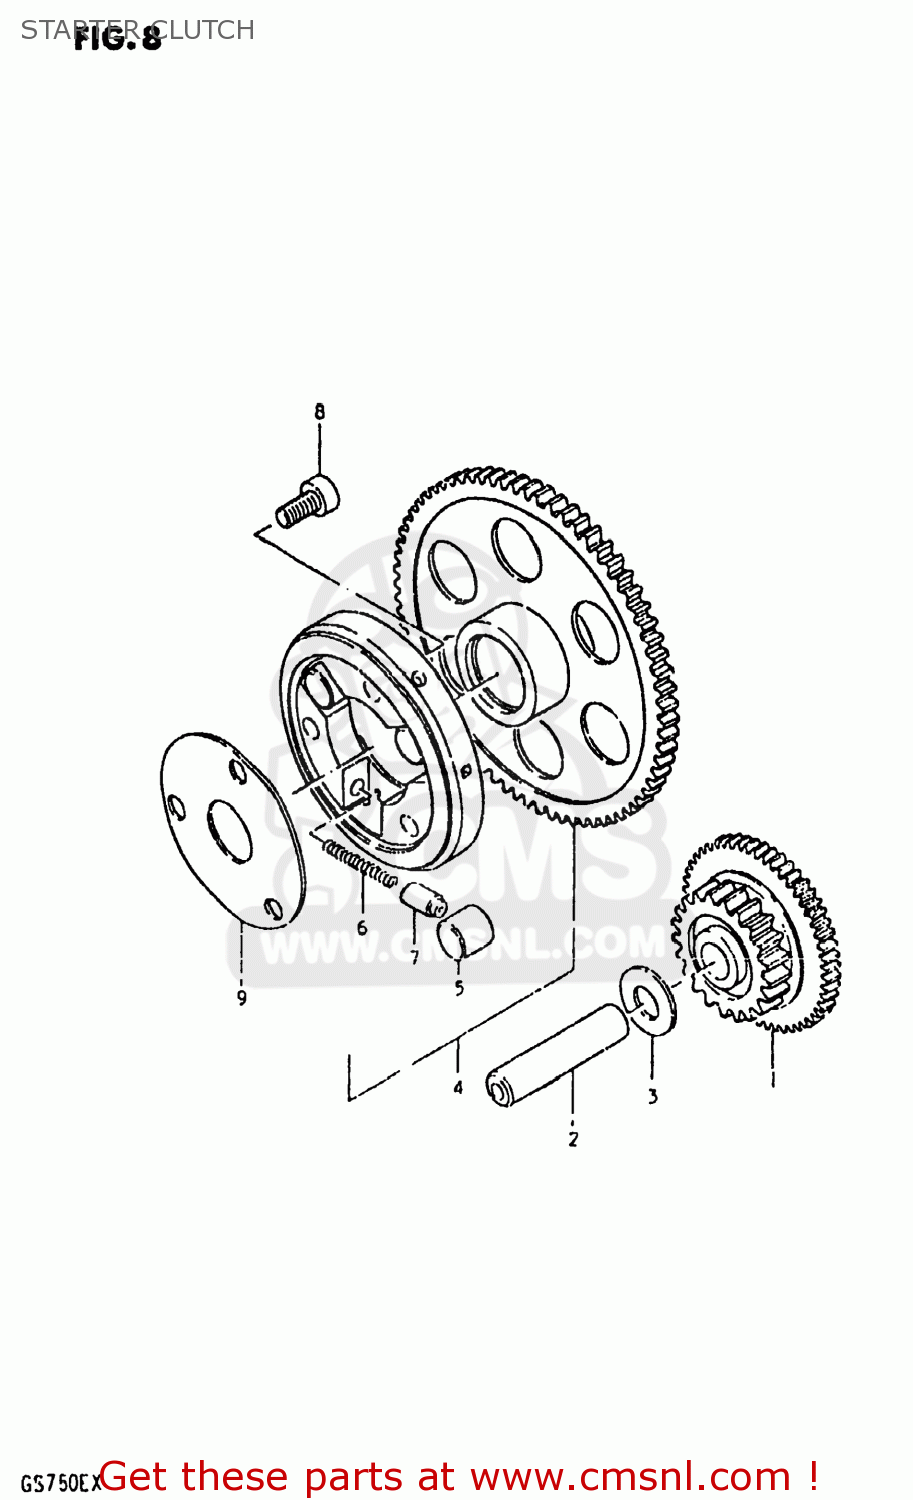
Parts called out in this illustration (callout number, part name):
1	GEAR,STARTER IDLE
2	PIN(7.4X13X56)
3	WASHER
4	CLUTCH SET,STARTER
5	ROLLER(15X13)
6	SPRING
7	PIECE,PUSH
8	BOLT
9	SHIM,STARTER CLUTCH HUB
